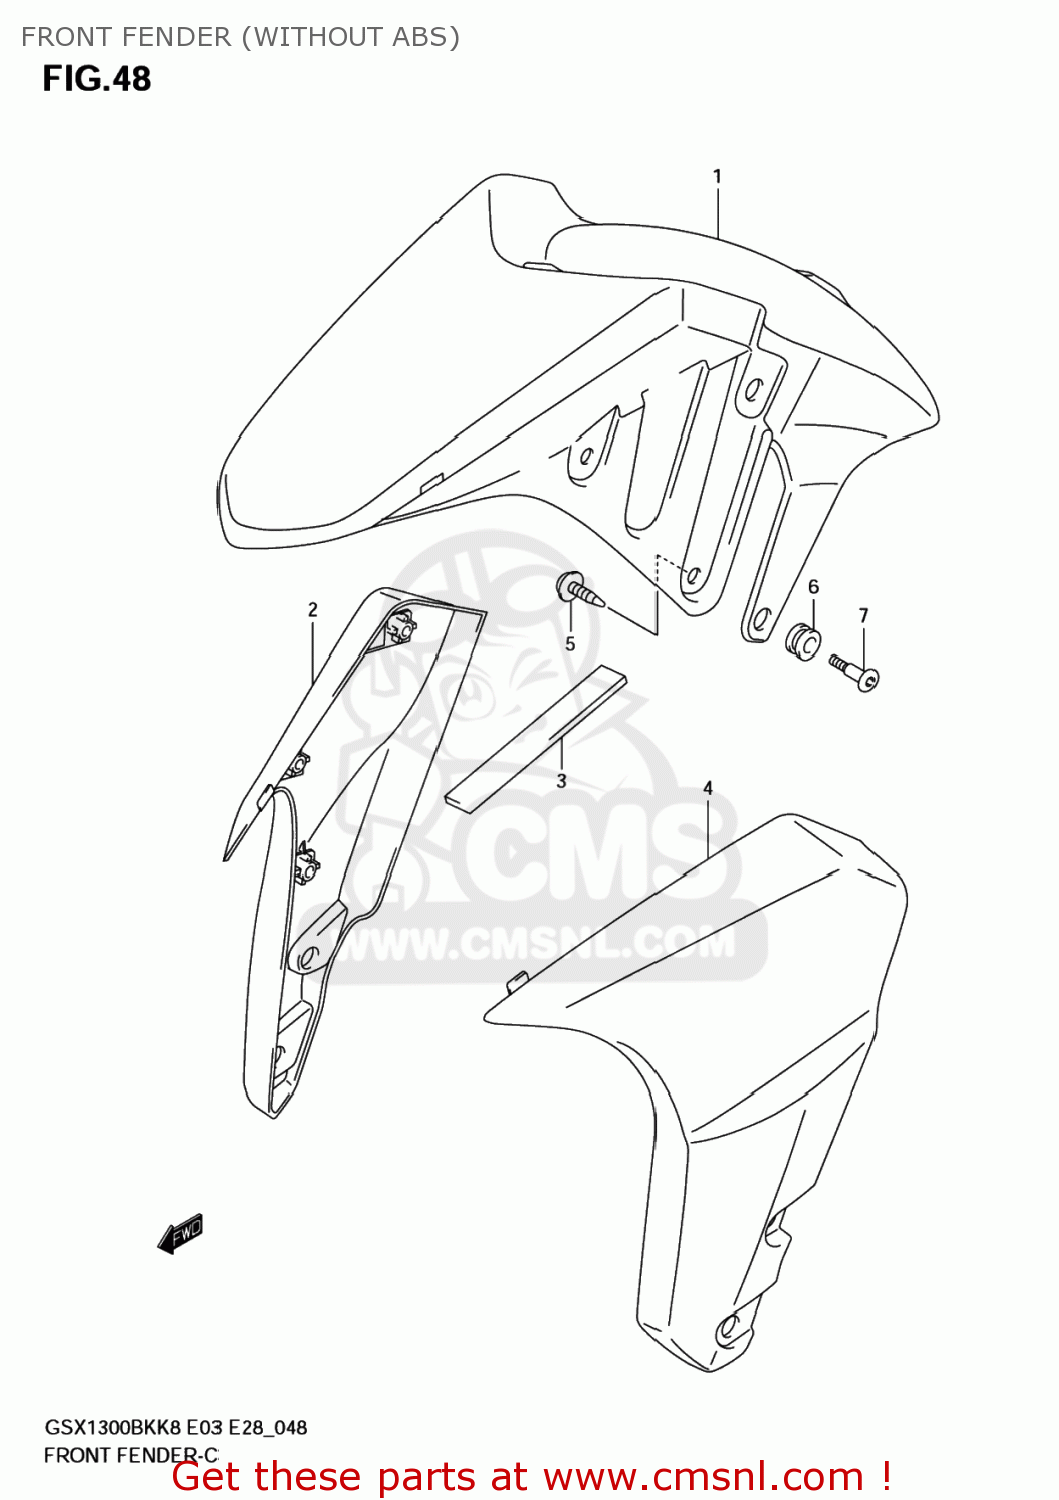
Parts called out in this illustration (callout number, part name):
1	FENDER,FR
2	COVER,FR FENDER SIDE,R(BLACK)
3	CUSHION,FR FENDER SIDE COVER
4	COVER,FR FENDER SIDE,L(BLACK)
5	SCREW(5X15)
6	CUSHION
7	SCREW(6X16)
